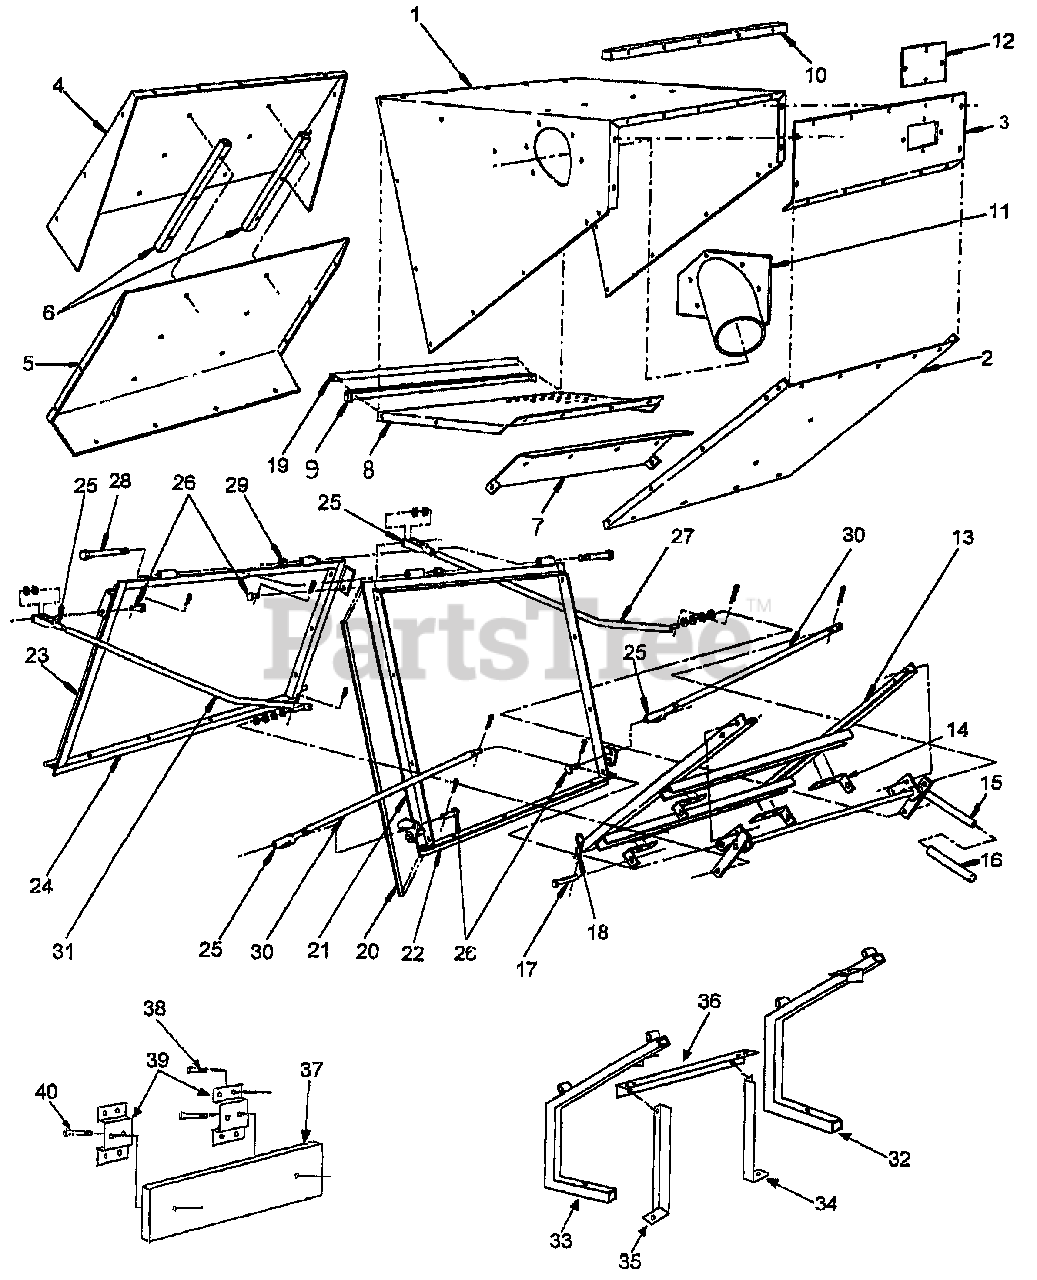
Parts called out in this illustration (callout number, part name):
1	CATCHER BODY
2	CATCHER BOX BOTTOM
3	CATCHER FRONT
4	OUTER DOOR SHELL
5	INNER DOOR SHELL
6	DOOR VENT TUBING
7	INTAKE DEFLECTOR
9	REAR SCREEN SUPPORT
10	FRONT BUMPER
11	INTAKE TUBE 6"
12	VIEWING WINDOW
13	CATCHER FRAME BASE
14	BASE FRAME TAB
15	LEVER DUMP ASSEMBLY
16	VINYL GRIP 5
17	CLEVIS PIN 1/2" X 3"
18	HAIR SPRING COTTER #6
19	RUBBER SEAL
21	CATCHER FRAME OPENING
22	BOTTOM CATCHER FRAME OPENING
23	CATCHER DOOR FRAME
24	BOTTOM DOOR FRAME
25	ADJUSTABLE YOKE END 3/8" -24
26	CLEVIS PIN 3/8" X 1-1/8"
27	HINGE ROD LF
31	HINGE ROD RT
32	LEFT CATCHER MOUNTING FRAME
33	RIGHT CATCHER MOUNTING FRAME
34	RIGHT CATCHER FRAME SUPPORT
35	LEFT CATCHER FRAME SUPPORT
36	CATCHER MOUNTING FRAME CROSS BAR
37	WEIGHT BAR
39	WEIGHT MOUNTING BRACKET
